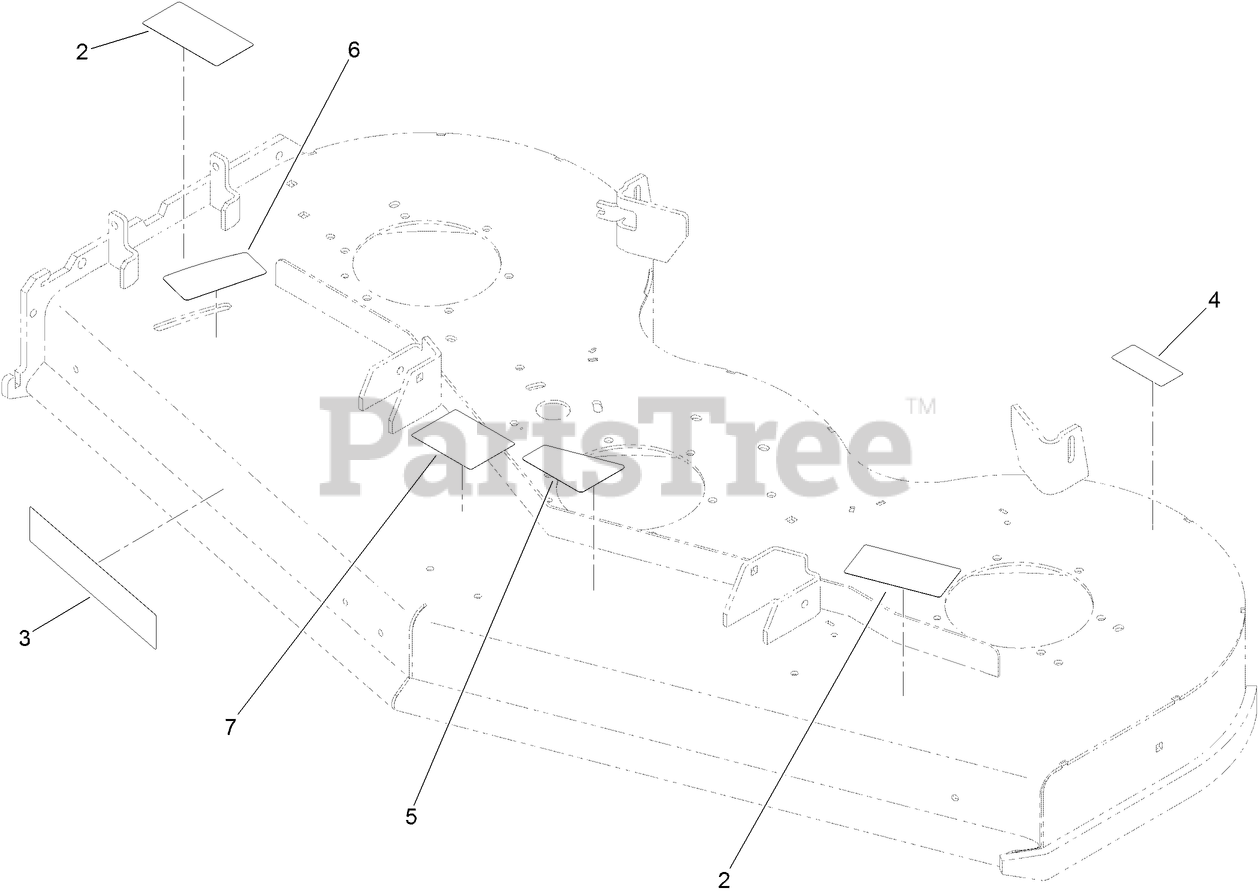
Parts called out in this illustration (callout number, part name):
2	DECAL-DANGER
4	DECAL-BOLT TORQUE
5	DECAL-BELT, TENSION (CE)
6	DECAL-ADJUSTMENT, BAFFLE
7	DECAL-SCALP, ANTI
